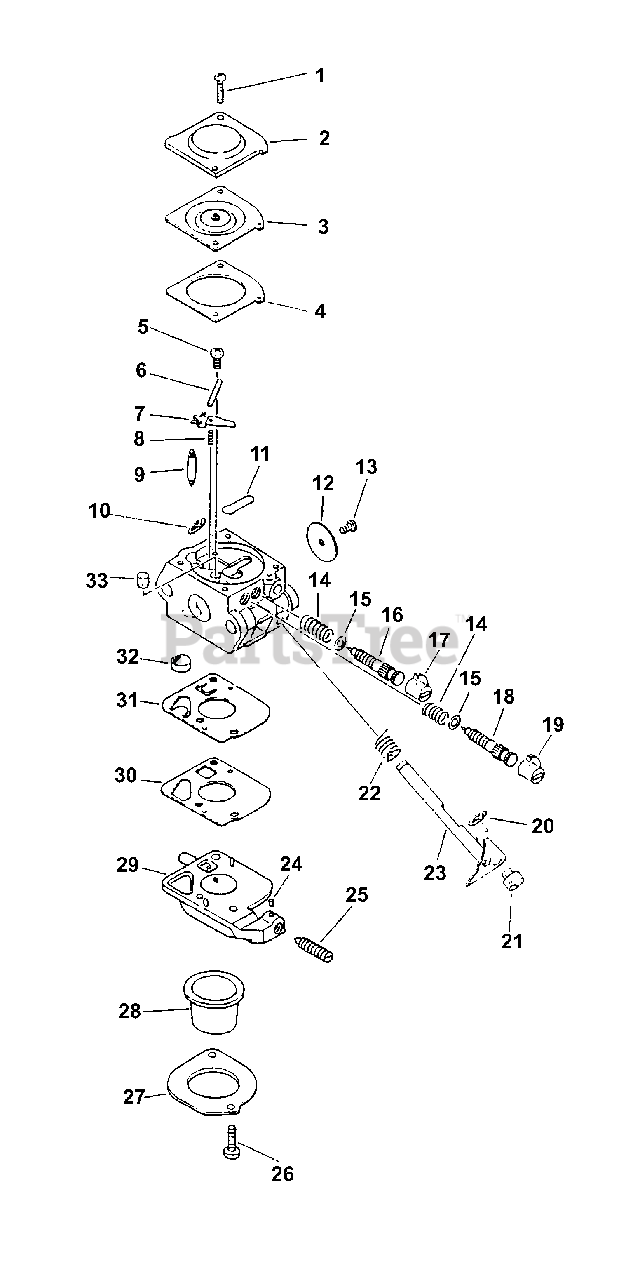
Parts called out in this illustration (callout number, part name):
2	COVER, METERING
3	DIAPHRAGM
4	GASKET, DIAPHRAGM
5	SCREW, METERING LEVER PIN
6	PIN, METERING LEVER
7	LEVER, METERING
8	SPRING
9	VALVE, NEEDLE
10	RING, RETAINING
11	PLUG, WELCH
12	VALVE, THROTTLE
16	NEEDLE - LOW SPEED
17	CAP, LIMITER
18	NEEDLE - HIGH SPEED
19	CAP, LIMITER
20	RING, RETAINING
22	SHAFT, THROTTLE
23	SPRING, RETURN
24	PIECE, FRICTION
25	SCREW, IDLE ADJUST
26	SCREW, RETAINER
27	RETAINER, PURGE BULB
28	BULB, PURGE
29	BASE, PURGE
30	GASKET, PUMP
31	DIAPHRAGM, PUMP
32	STRAINER
33	NOZZLE, CHECK VALVE
